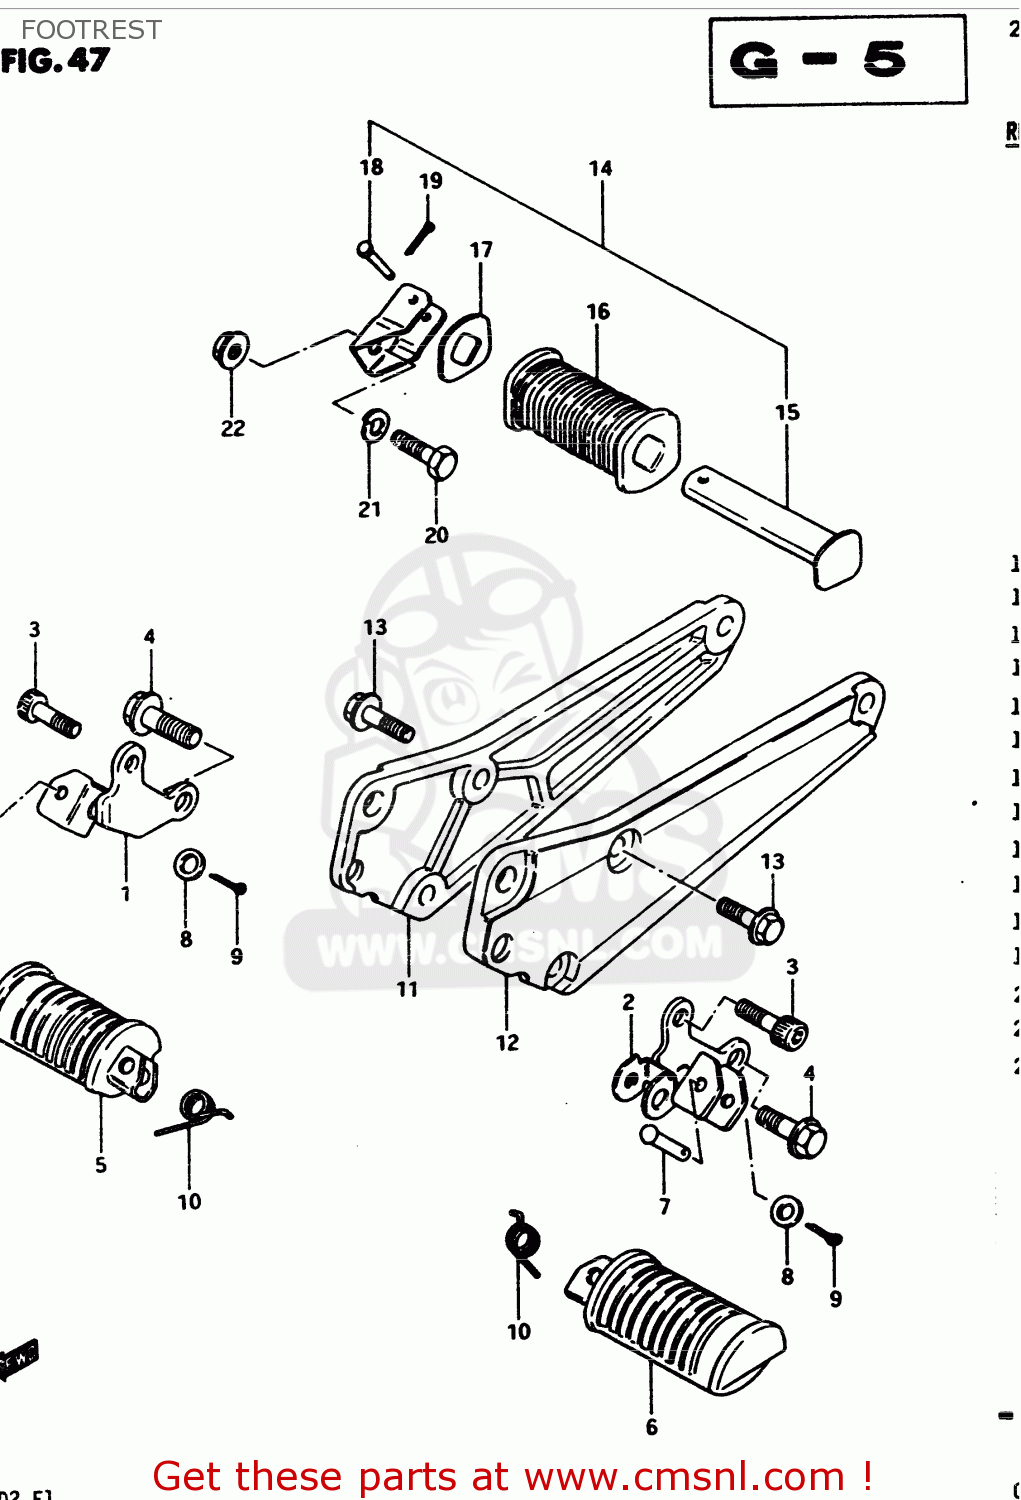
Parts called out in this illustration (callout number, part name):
1	BAR,FR FOOTREST,R
2	BAR,FRONT FOOTREST,LEFT
3	BOLT
4	BOLT
5	RUBBER,PILLION FOOTREST,R
6	RUBBER,PILLION FOOTREST,L
7	PIN
8	WASHER
9	PIN 20X20
10	SPRING
11	BRACKET,MUFFLER,RIGHT
12	BRACKET,MUFFLER,LEFT
13	BOLT
14	FOOTREST ASSY,PILLION,R
15	BAR,REAR FOOTREST,LEFT
16	RUBBER,PILLION FOOTREST
17	WASHER,FOOTREST RUBBER
18	PIN
19	PIN 20X20
20	BOLT,M10X1.25X
21	LOCK WASHER
22	NUT
